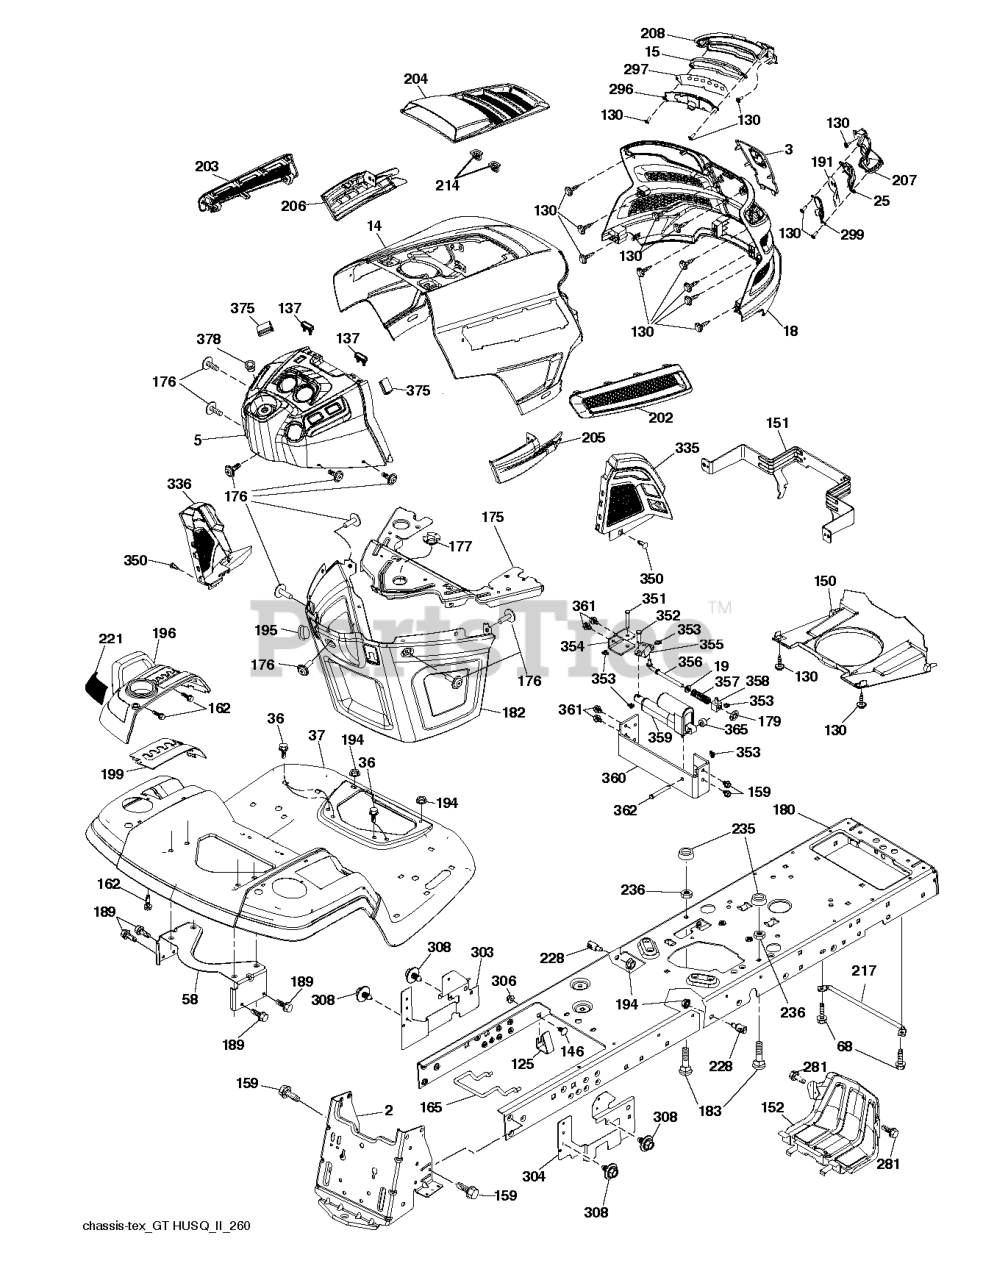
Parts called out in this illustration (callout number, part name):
2	DRAWBAR.STGT
3	APPLIQUE.SUBASM.GT.HUSQ.II
5	DASH.GT2.UPPER.RND.ELD.CP.498
14	HOOD.ASM.HUSQVARNA.GT.TEX.ORAN
15	LED LIGHT.LH
18	GRILLE SUBASM.GT.II.LOW.HDLGHT
19	WASHER
25	LENS.RH
36	SCREW 5/16"
37	FENDER HUSQVARNA GT MS668 - HU
58	BRKT.SUPPORT.FNDR/TANK
68	SCR 5/16-18 X 1/2 SELFTAP ZN
125	CLIP.FUEL.LINE
130	SCREW.#10 X 0.750.BOS
137	BUMPER DASH
146	BOLT.RDHD.SHT.SQNK.3/8-16X5/8
150	AIR.DUCT.GTV.BLACK
151	BRACKET.PIVOT.HOOD.GT.HUSQ.II
152	SHIELD.BROWNING.PNT.GT.V2
159	SCREW, 3/8-16X3/4
162	SCREW.HI-LO.CONSOLE
165	SUPPORT.TANK.REAR.B/TE
175	PLATE.PNT.CROSSMEMBER.HUSQ/PRE
176	SCREW.#10-24X5/8.RN.QU
177	BUSHING STEERING
180	CHASSIS.LT/GT.BOLTED
182	DASH.LOWER.COMMON.12V.ADAPTOR
183	BOLT.5/16-18X1-1/4 FULL THD
189	SCREW
191	INSERT INFLECT.RH
194	NUT LOCK HEX FLANGE 5/16-18
195	PLUG.HOLE.DASH.LOWER.12V.BLK
196	CONSOLE.ASM.DECKLIFT.HUSQGT.DL
199	PLATE.DECK.LIFT.HUSQVARNA.GT
202	VENT.SIDE.RH.GT.HUSQ.II.
203	VENT.SIDE.LH.GT.HUSQ.II.498
204	VENT.TOP.ASM.HUSQ.GT2
205	SIDE.TRIM.RH.GT.HUSQ.II
206	SIDE.TRIM.LH.GT.HUSQ.II.GRAY
207	BEZEL GT2 LED RH W/ LOWER.ATT
208	BEZEL GT2 LED LH W/ LOWER ATT
214	CLIP.RETAINER.TINNER.
217	ROD.PIVOT.HOOD
221	REFLECTOR.LH.TEX GT HU
228	STUD.FASTNER.W/ANTI-ROTATE
235	SPACER FENDER
236	NUT.CENTERLOCK.5/16-
281	SCREW 3/8-16X1
296	LED LIGHT.LH
297	INSERT REFECT LH
299	LED LIGHT.RH
303	SHIELD.LWR.LH.LTGT.NON30
304	SHIELD.LWR.RH.LTGT.NON30.NOTCH
306	NUT LOCK FLG 3/8-16 UNC
308	BOLT.5/16-18UNCX3/4 W/SEMS.BLK
335	COVER.LOWER.DASH.RH.BLACK
336	COVER-LH.LOWER.DASH.GT2.BLACK
350	CLIP.X-MAS.TREE
351	PIN.CLEVIS.375X2.125
352	PIN.CLEVIS.(.375 X 1.25)
353	CLIP RETAINER
354	SUPPORT.BELLCRANK
355	BELLCRANK.PIVOT.LOCK.DIFF
356	LINK.LOCK.DIFF
357	SPRING.COMPRESSION
358	GUIDE.SWIVEL
359	ACTUATOR.ELECTRIC
360	BRACKET.ACUATOR
361	SCREW LT.3/8-46X5/8
362	PIN.CLEVIS.(.375 X 2.42)
365	SPACER.NYLON.75" X .4375
375	BUMPER CLIP-ON. DASH 1"
378	BUSHING FLANGE; PLASTIC
